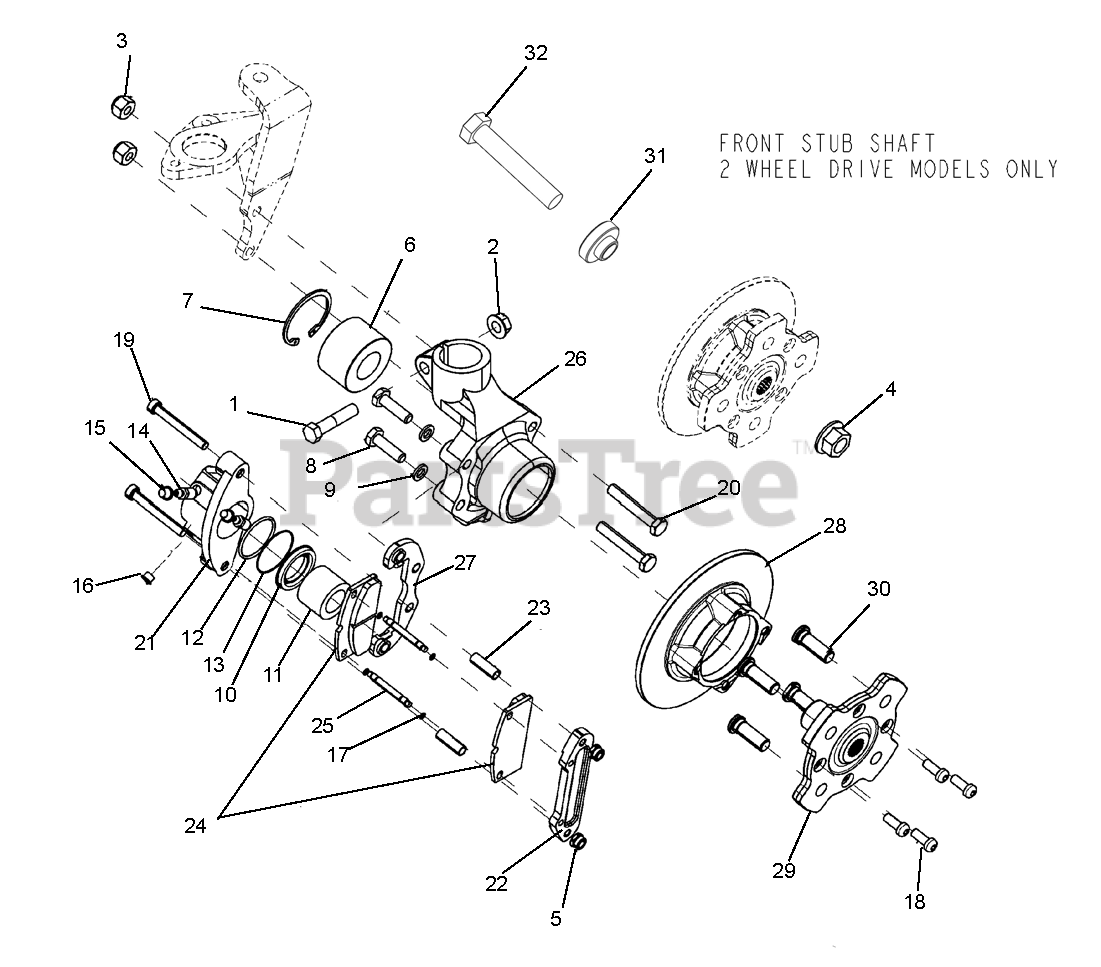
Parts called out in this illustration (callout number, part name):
1	BLT-HEX .38-16X2.00 GR8 YWZC
2	@NUT-LK-NYL .38-16 YWZC
3	NUT HEX NYLOCK M10X1.5 PLT
4	NUT HEX FLG T LCK M16X1.5 PLT
5	CMEX NUT M8
6	CMEX BALL BEARING 60,05X30X37
7	CMEX SEEGER
8	CMEX SCREW M 10 X 1.25 X 35
9	CMEX GROWER 10
10	CMEX DUST BOOT RING
11	CMEX CAP
12	CMEX SEALING RING
13	CMEX RUBBER DUST BOOT
14	CMEX BLEEDER SCREW
15	CMX BOOT
16	CMEX PLUG
17	CMEX DUST BOOT RING
18	CMEX SCREW M8 X 20
19	CMEX SCREW M8 X 65
20	CMEX HHS M10X1.5X50 PLT
21	CMEX CALIPER BODY
22	CMEX REACTION BRACKET
23	CMEX SPACER
24	BRAKE PAD KIT (COMP. 2 WHEELS)
25	CMEX PIN
26	CMEX WHEEL PIVOT
27	CMEX CALIPER CLAMPING PLATE
28	CMEX DISC BRAKE
29	CMEX FLANGE WITH STUDS
30	CMEX STUD
31	SPCR, STUB BOLT
32	BLT-HEX M16-1.5 X 90 8.8 YWZC
